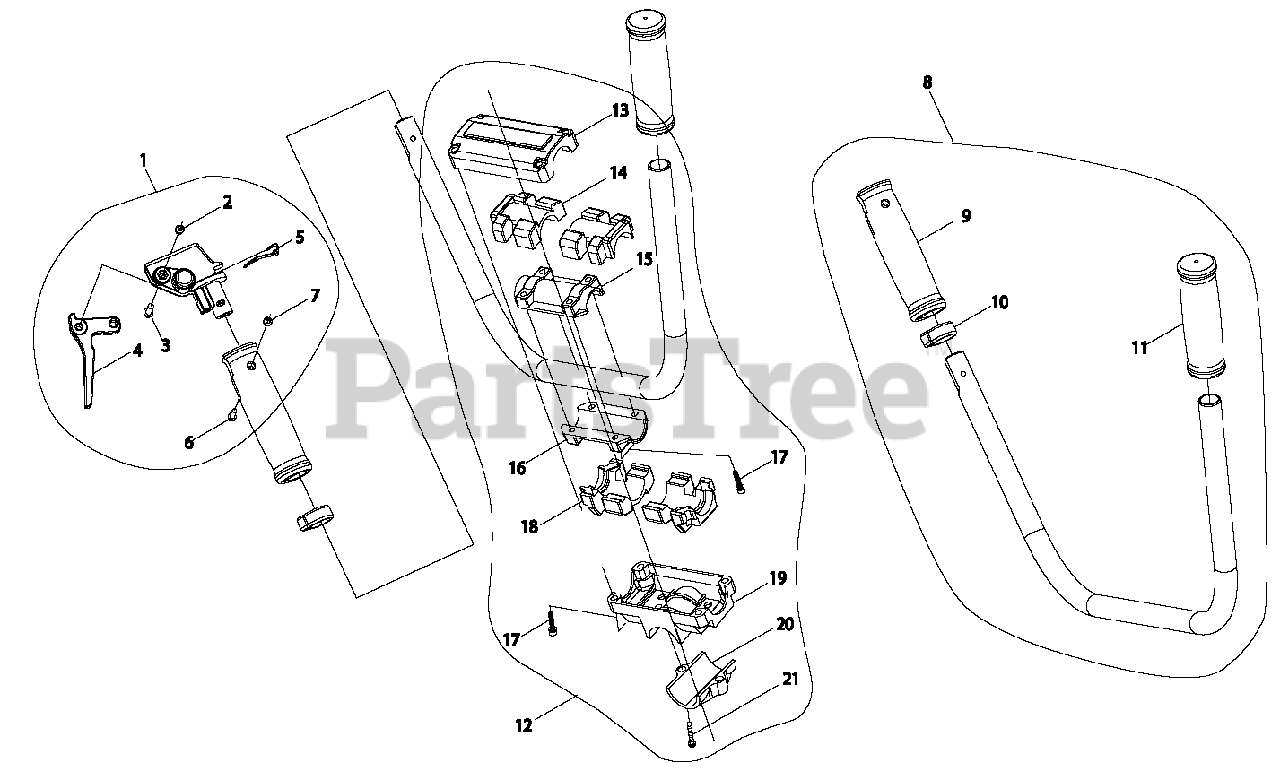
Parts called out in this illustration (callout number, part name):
1	THROTTLE CONTROL ASSY
2	NUT, LOCK M5
3	BOLT
4	TRIGGER, THROTTLE
5	STOPPER, THROTTLE TRIGGER
6	BOLT M4×24
7	NUT, NYLON M4
8	HANDLEBAR ASSY
9	GRIP, RIGHT
10	HOLDER, THROTTLE CABLE
11	GRIP, LEFT
12	BRACKET KIT, HANDLEBAR
13	BRACKET, UPPER
14	CUSHION, UPPER
15	CLAMP, UPPER
16	CLAMP, LOWER
17	BOLT M5×25
18	CUSHION, LOWER
19	BRACKET, LOWER
20	BRACKET, MOUNTING
21	SCREW M6×25
